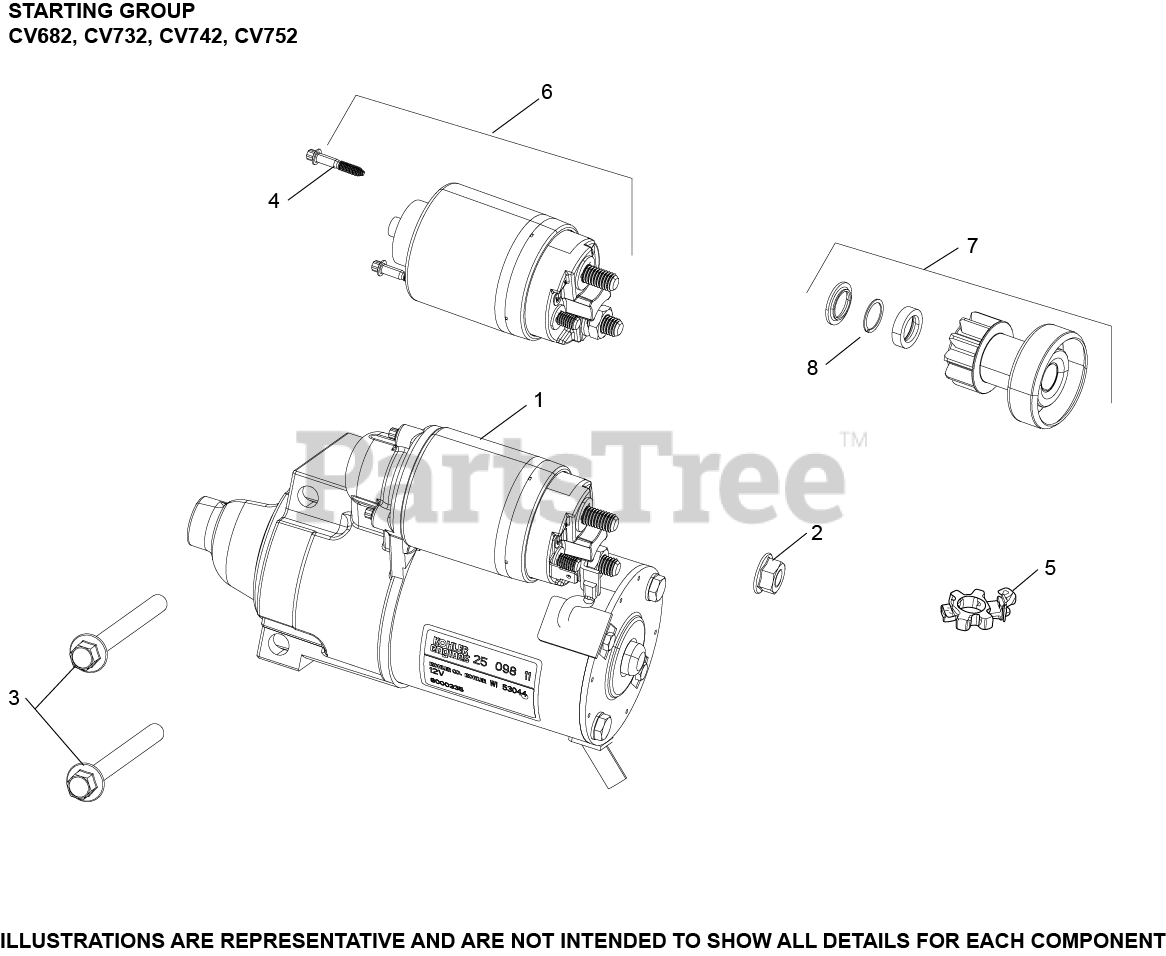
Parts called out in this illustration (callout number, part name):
1	ELECTRIC STARTER - SOLENOID SHIFT USE 25 098 20-s
2	NUT, FLG M8X1.25
3	SCREW, FLG M8X1.25X80
4	SCREW, EXTERNAL TORX HEAD
5	KIT, BRUSH HOLDER
6	SOLENOID, ASSEMBLY-USE 25 435 06-S
7	KIT, STARTER PINION
8	RING, RETAINING
